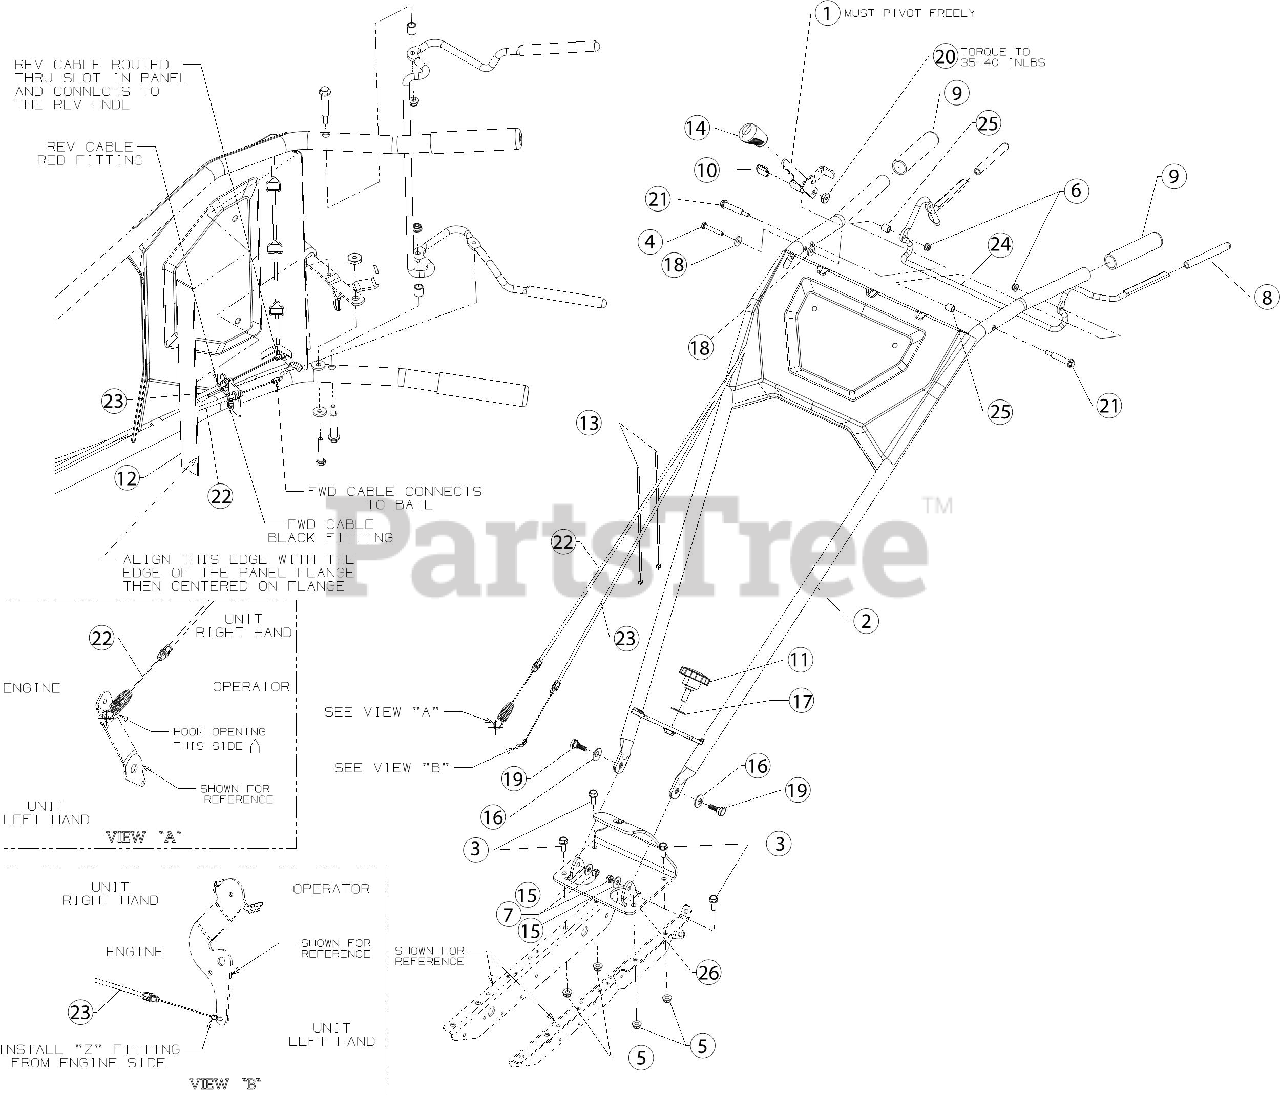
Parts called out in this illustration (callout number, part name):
1	REVERSE HANDLE ASSEMBLY
2	HANDLE ASSEMBLY
3	SCREW 5/16-18 X .875 GR5
4	BOLT 1/4-20X1.62 GR5
5	FLANGE LOCK NUT 5/16-18
6	FLANGE LOCK NUT
7	HEX NUT
8	CLUTCH GRIP
11	STAR KNOB 3/8-16
12	TAPE FOAM 1.25 X 13.53 X .10
14	BRAKE HANDLE GRIP
15	FLAT WASHER
16	BELL WASHER
17	BELL WASHER
18	FLAT WASHER
19	SHOULDER SCREW .437
20	SHOULDER SPACER
21	SHOULDER SCREW .375 X 1.62 X 1/4-20
22	FORWARD CABLE
23	REVERSE CABLE
24	CLUTCH BAIL
26	HANDLE MOUNT PLATE
